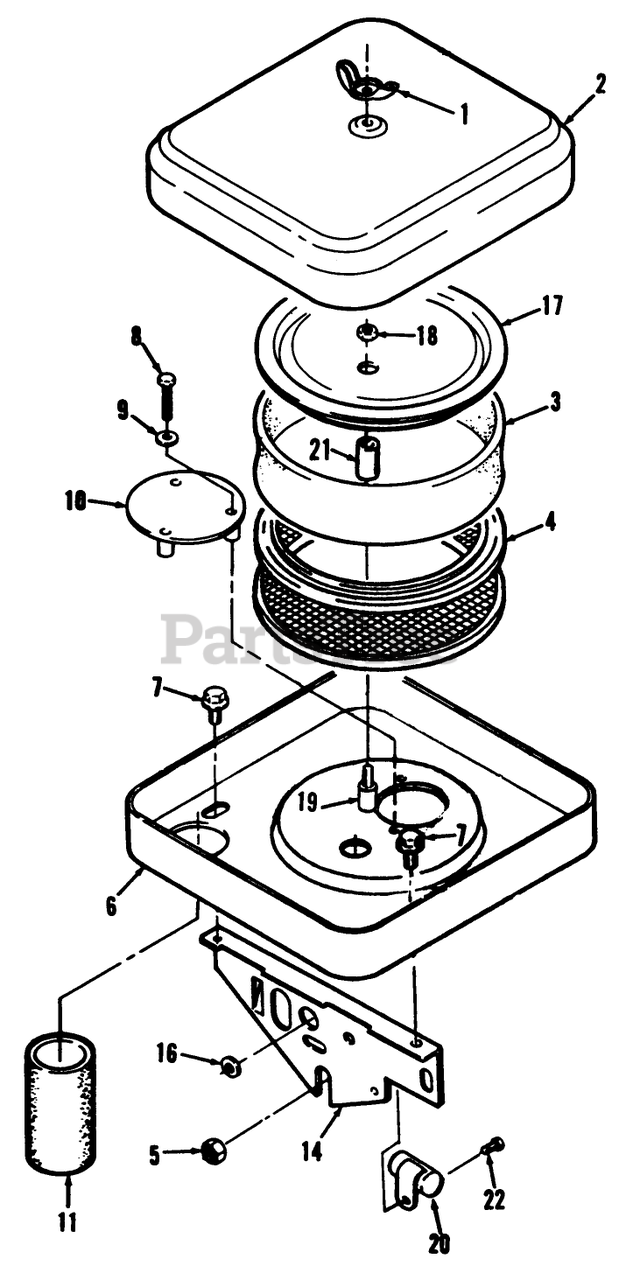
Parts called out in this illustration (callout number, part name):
2	AIR-CLEANER COVER
3	AIR CLEANER ELEMENT
4	AIR-CLEANER ELEMENT
5	Washer
6	Housing, Air Cleaner
7	SCREW-TAPPING
8	Screw Hex Hd. #10-32 x 1-1/2
9	Flat Washer #10
10	AIR DEFLECTOR PLATE
11	TUBE-AIR INTAKE
14	SUPPORT-AIR CLEANER
16	GROMMET
17	ELEMENT COVER KIT
18	NUT - HEX
19	Spacer, Air Cleaner Stud
20	CONDENSER
21	SPACER-1" LG
22	SCREW #10-32 X 5/8
